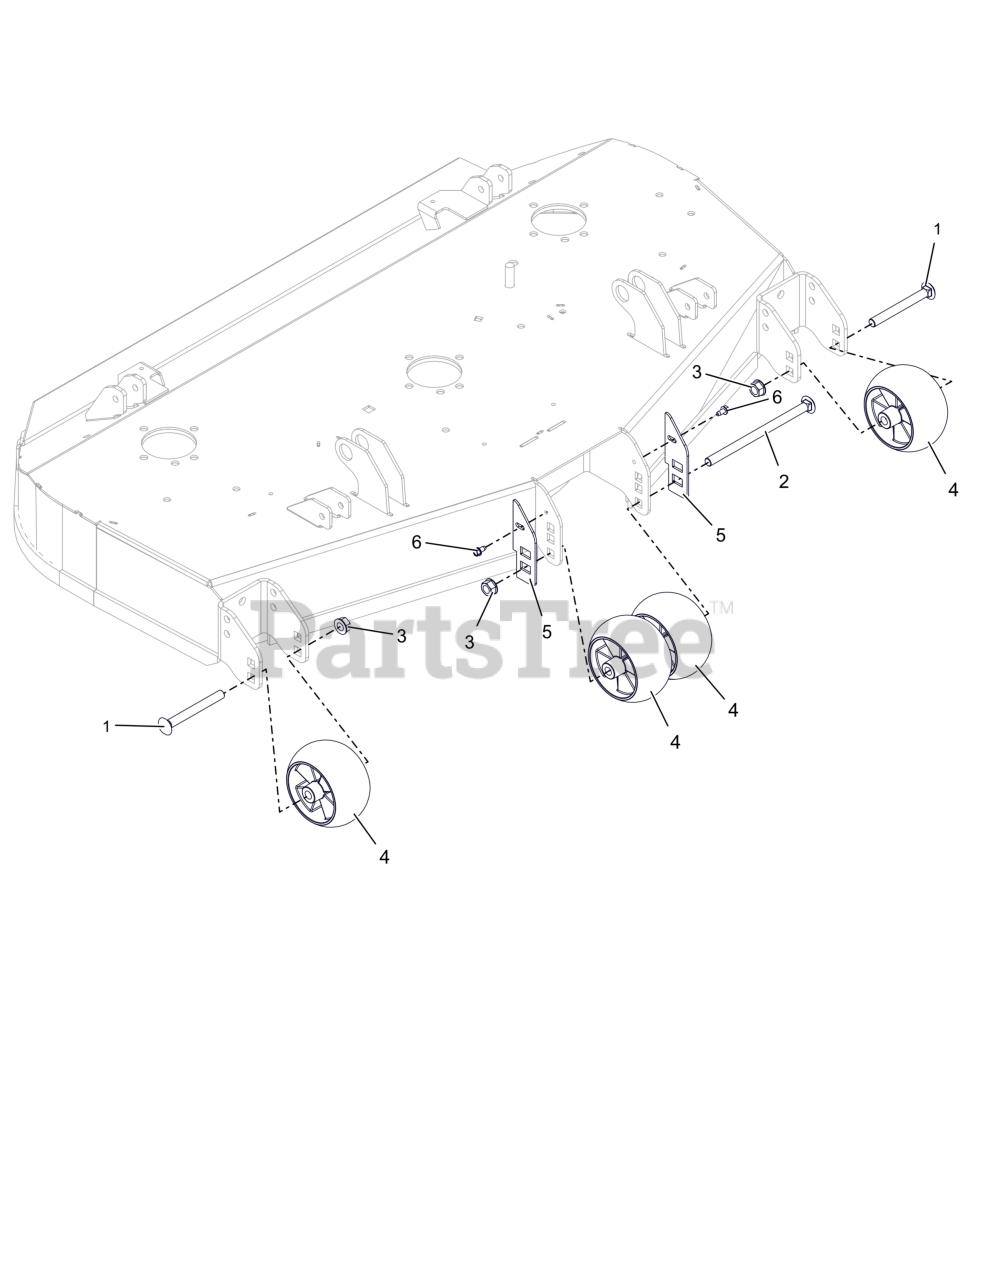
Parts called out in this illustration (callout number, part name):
1	BOLT, RHNS .50-13X4.50 G5 ZCC NS
2	BOLT, RHNS .50-13X8.00 G5 ZCC NS
3	NUT-LK-CTR-FLG .500-13 GG ZCC
4	WHEEL, ANTI SCALP - 5X3 CTR W/RIBS
5	PLATE, ANTI SCALP WHEEL 60" (ORANGE)
6	SCR-TAP .25-20X.50 HWH ZCC
